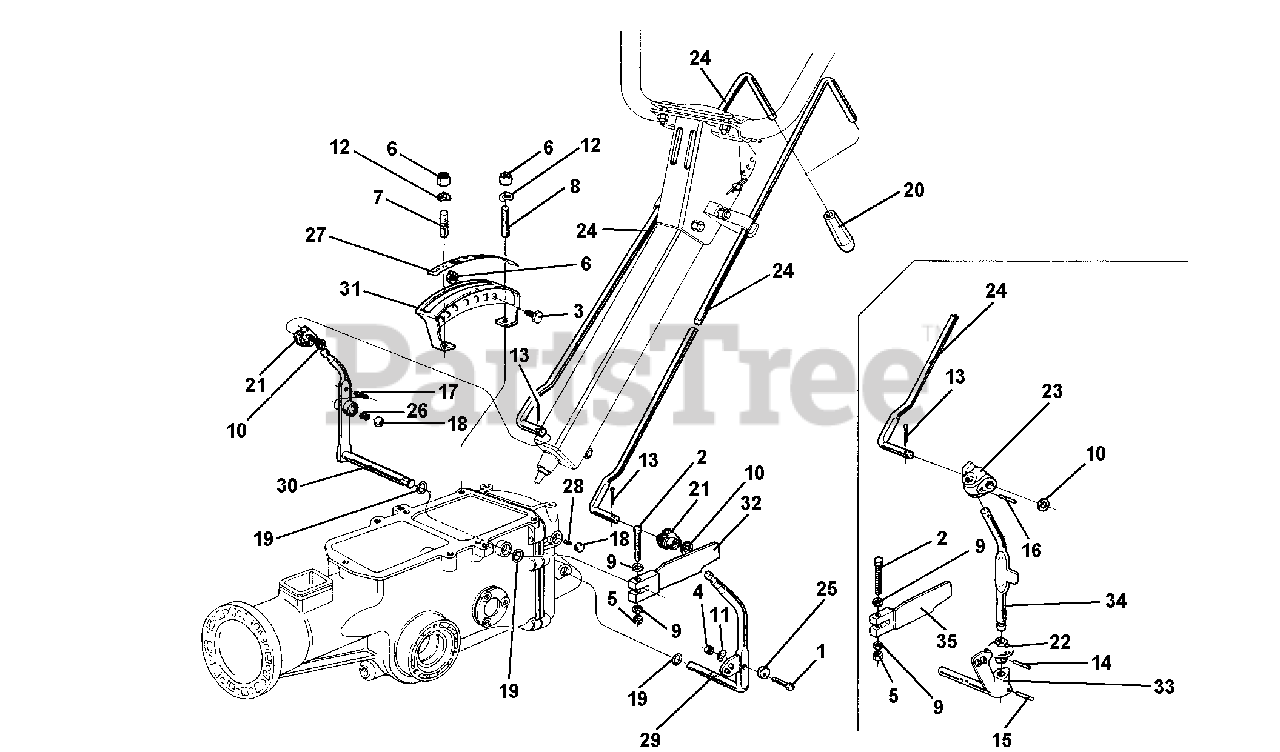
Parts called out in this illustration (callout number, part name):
1	SCREW M6 X 25
2	SCREW M6 X 40
3	SCREW M8 X 14
5	NUT, SELF LOCKING M6
6	NUT, SELF LOCKING M8
7	STUD M8 X 38 X 14 X 20
8	STUD M8 X 46 X 16 X 16
9	WASHER, FLAT 6.4
10	WASHER P10.5 X 18
11	WASHER, LOCK 6.4
12	WASHER, LOCK 8.4
14	LOCKING PIN 4 X 20 SPIRAL
16	LOCKING PIN 4 X 24 SPIRAL
17	LOCKING PIN SPIRAL
18	BALL 15/32 RIV RB-11.906
19	O-RING 115 11.91 X 2.62
21	JOINT, D 10
22	P.T.O. STOP RING
23	P.T.O. ARTICULATION
24	ROD, CONTROL, POWER TILLER
27	PLATE 5 SPEEDS WALKING TRAC
28	P.T.O. SPRING
29	P.T.O. LEVER
30	GEARBOX LEVER
32	P.T.O. LOCKOUT
33	P.T.O. CONTROL PIN
34	P.T.O. CONTROL LEVER
35	P.T.O. LOCKOUT
